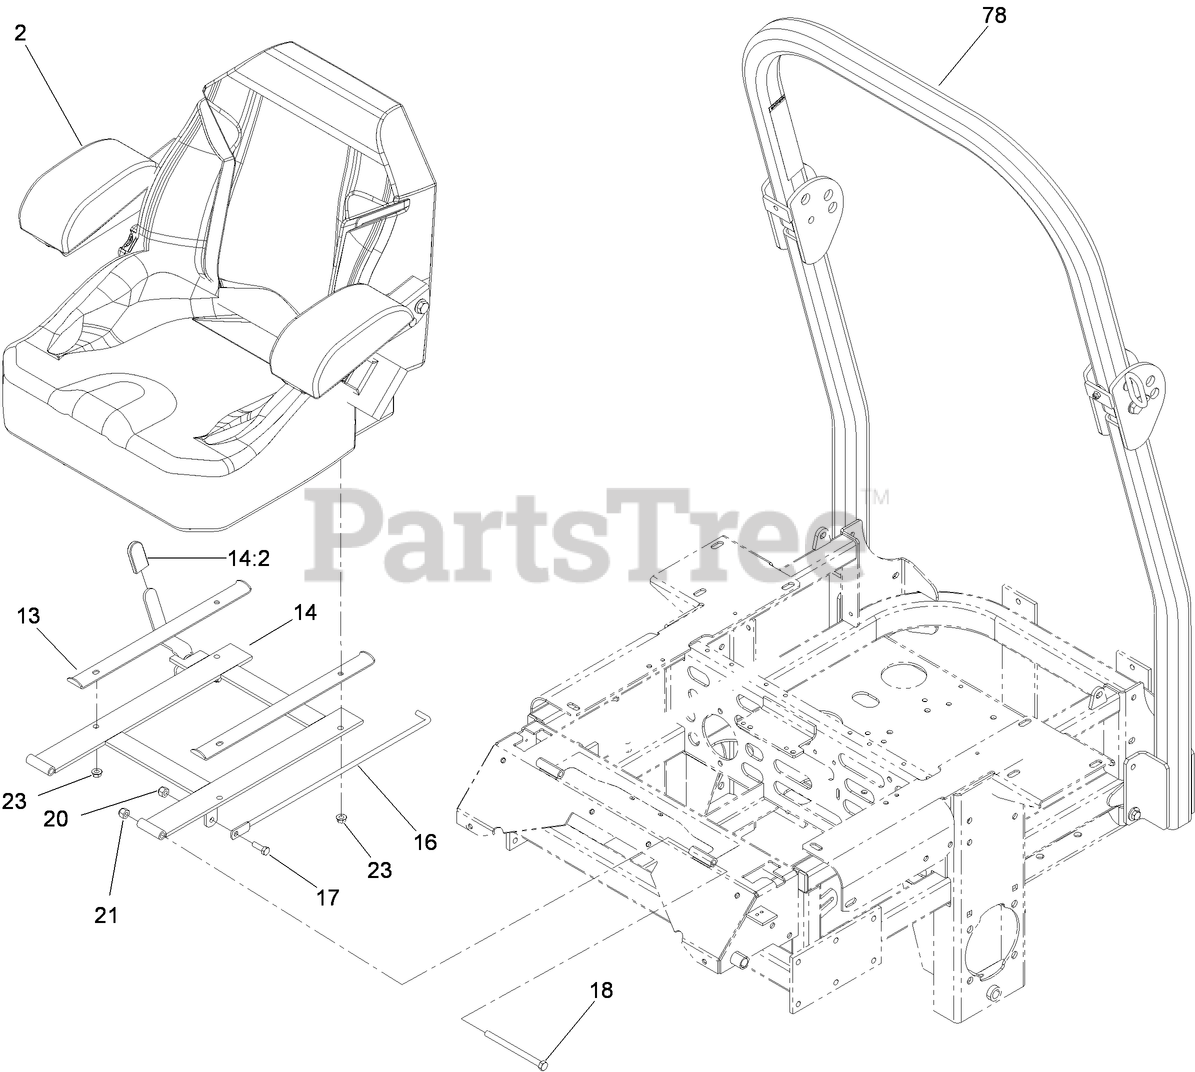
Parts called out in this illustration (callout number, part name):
2	SEAT-STANDARD
13	STOP-SEAT
14	SEAT FRAME AND LATCH ASM
14:2	GRIP-LEVER
16	ROD-HOLDUP, SEAT
17	SCREW-HH
18	SCREW-HH
20	NUT-LOCK, NI
21	NUT-LOCK, NI
23	NUT-HF
78	ROPS KIT
